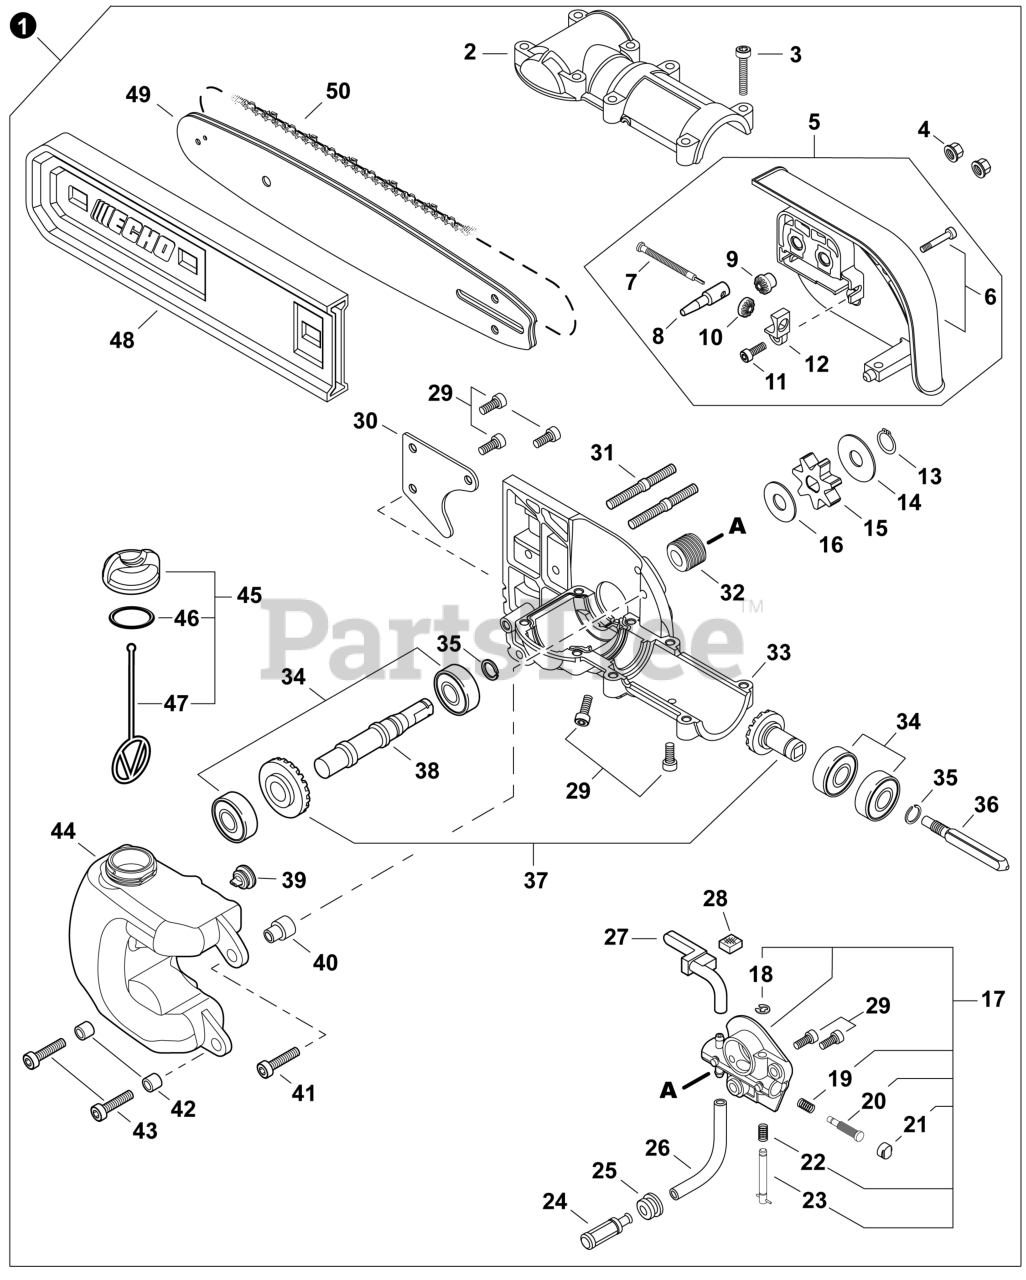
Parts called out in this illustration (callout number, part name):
1	CUTTING HEAD KIT
2	COVER, GEAR CASE
3	BOLT, TORX 5x25
4	NUT, FLANGE M6
5	SPROCKET GUARD ASSY
6	GUARD, SPROCKET
8	TENSIONER, CHAIN
9	GEAR - 14 TOOTH
10	GEAR - 14 TOOTH
11	SCREW 4
12	COLLAR 8
13	RING, SNAP
14	WASHER 10
15	SPROCKET, DRIVE
16	WASHER 10
17	AUTO-OILER ASSY
20	PLUNGER ASSY
21	CAP, PLUNGER
23	ADJUSTER, OILER
24	FILTER, OIL
26	PIPE 3x6x70
27	PIPE, OIL OUTLET
28	PAD, FOAM
29	BOLT, TORX 5x10
31	BOLT, STUD 6
32	GEAR, WORM
33	CASE, GEAR
34	BEARING, BALL
35	RING, SNAP 12
36	CONNECTOR, DRIVESHAFT
37	GEAR SET, BEVEL
38	SHAFT, GEAR
39	VENT ASSY
40	COLLAR 6
41	BOLT, TORX 5x25
42	SPACER 6.2x7.8x6
43	BOLT, TORX 5x20
44	TANK, OIL
45	CAP ASSY
46	O-RING 18
47	CONNECTOR, CAP L= 60 MM
48	SCABBARD 10"
49	GUIDE BAR, 10"
50	SAW CHAIN 10"
